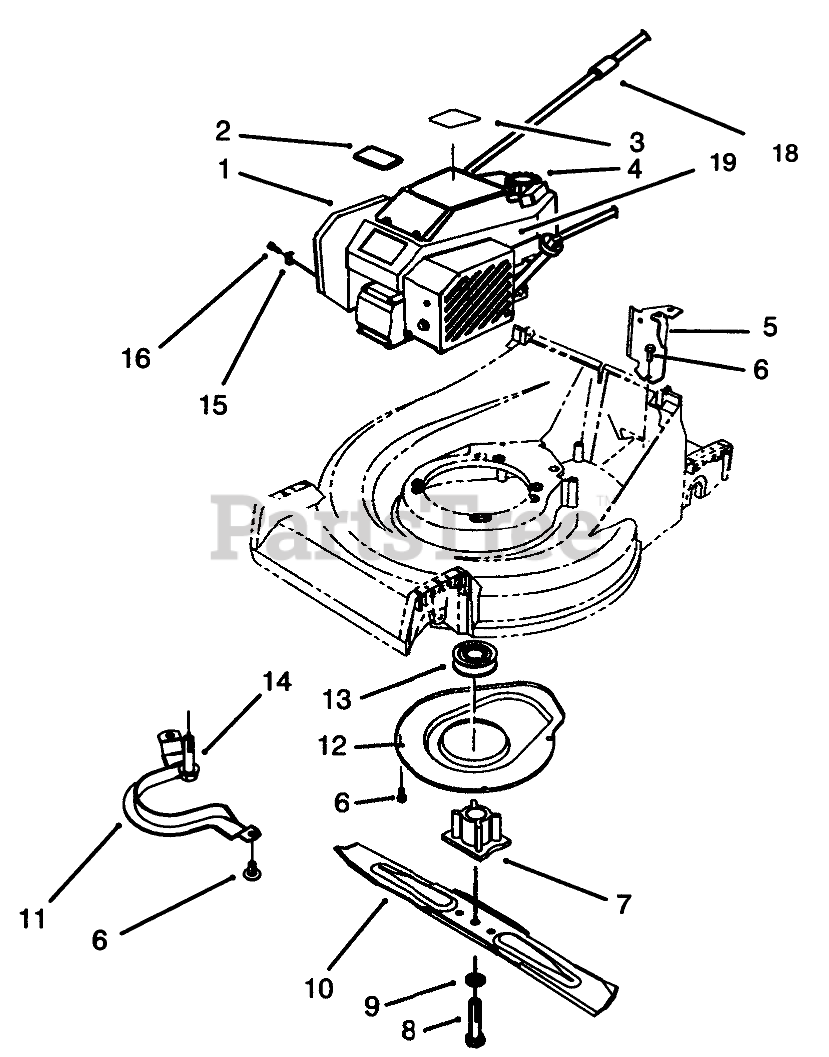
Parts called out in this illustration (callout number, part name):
1	Engine
2	PLATE-LOGO
3	DECAL - ENGINE
4	CAP-GAS
5	Bracket-Cable Support
6	SCREW-HWHTF
7	BLADE RETAINER
8	SCREW-BLADE
9	WASHER-LOCK
10	Key
11	Guide-Belt
12	Cover
13	PULLEY-DRIVE, ZONE START
14	SCREW-HWH
15	CLAMP-CASING
16	CLAMP SCREW F/W ENGINE
18	STOP-ROPE
19	COVER - BRAKE F/W
